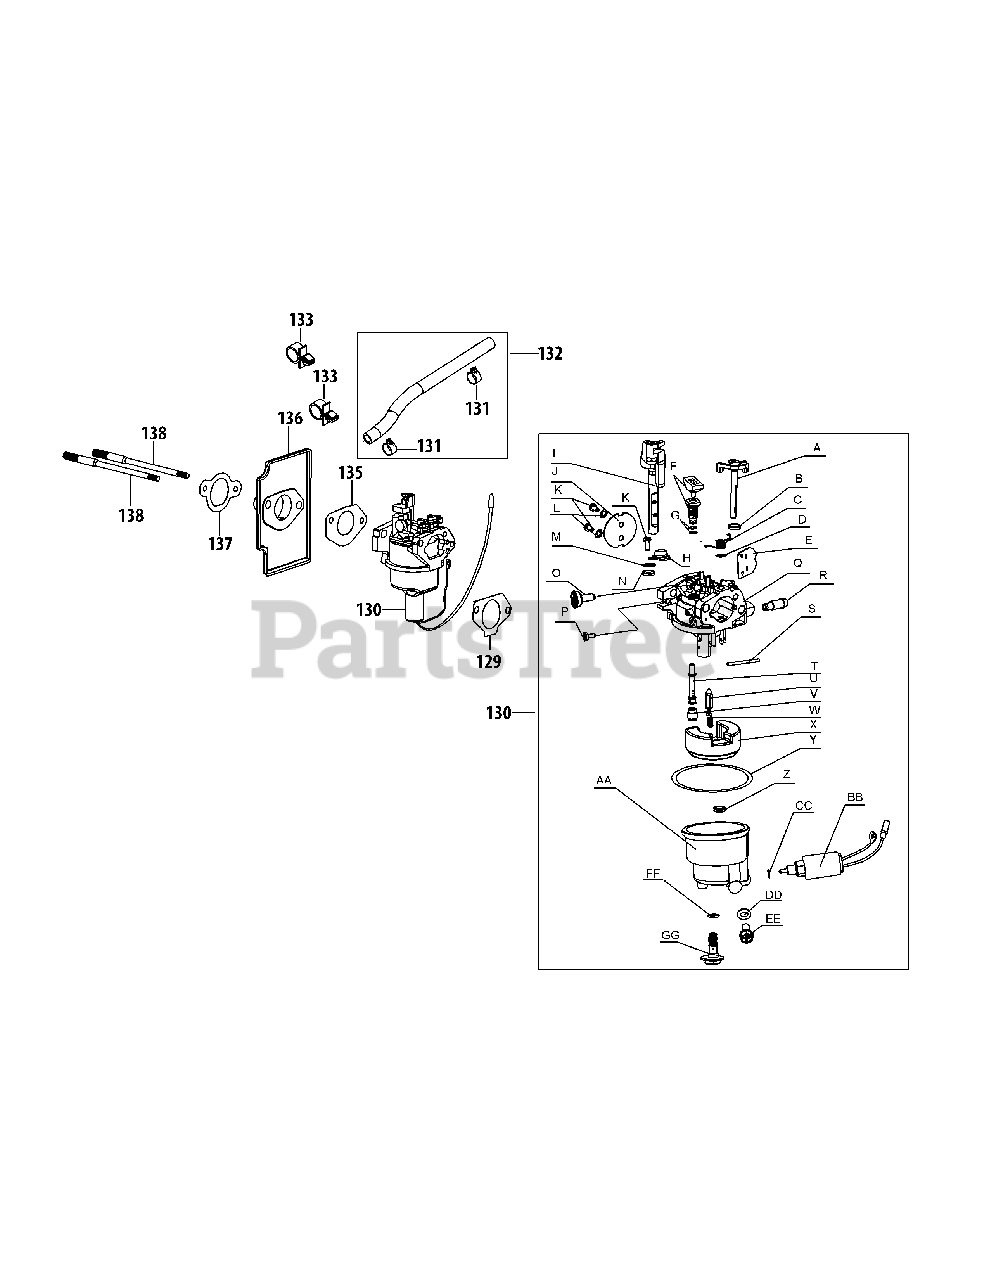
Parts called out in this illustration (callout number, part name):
129	Manifold Gasket
130	Carburetor Assembly
131	Fuel Hose Clamp
132	Fuel Line Kit
133	Plastic Support Clamp
135	Carburetor Gasket
136	Carburetor Insulator
137	Carburetor Insulator Gasket
A	Choke Shaft
B	Choke Shaft Fiber O-Ring
C	Choke Return Spring
D	Flat Steel Washer
E	Choke Plate
F	Idle Jet Assembly
G	Idle Jet O-Ring
H	Sheetmetal Housing
I	Throttle Shaft
J	Throttle Plate
L	Lock Washer
M	Nylon/Plastic O-Ring
N	Fiber O-Ring
O	SPEED IDLE SCREW
P	Idle Mixture Screw
Q	Carburetor Body
R	Fuel Inlet
S	HINGE FLOAT PIN
T	Emulsion Tube
U	NEEDLE VALVE
V	Main Jet
W	NEEDLE VALVE SPRING
X	CARBURETOR FLOAT
Y	FUEL BOWL O-RING
Z	Ring
AA	FLOAT BOWL
BB	FUEL SOLENOID
CC	Solenoid Valve Washer
DD	FUEL DRAIN PLUG GASKET
EE	FUEL DRAIN PLUG
FF	Ring
GG	SEAT/FUEL BOWL BOLT O-RING
